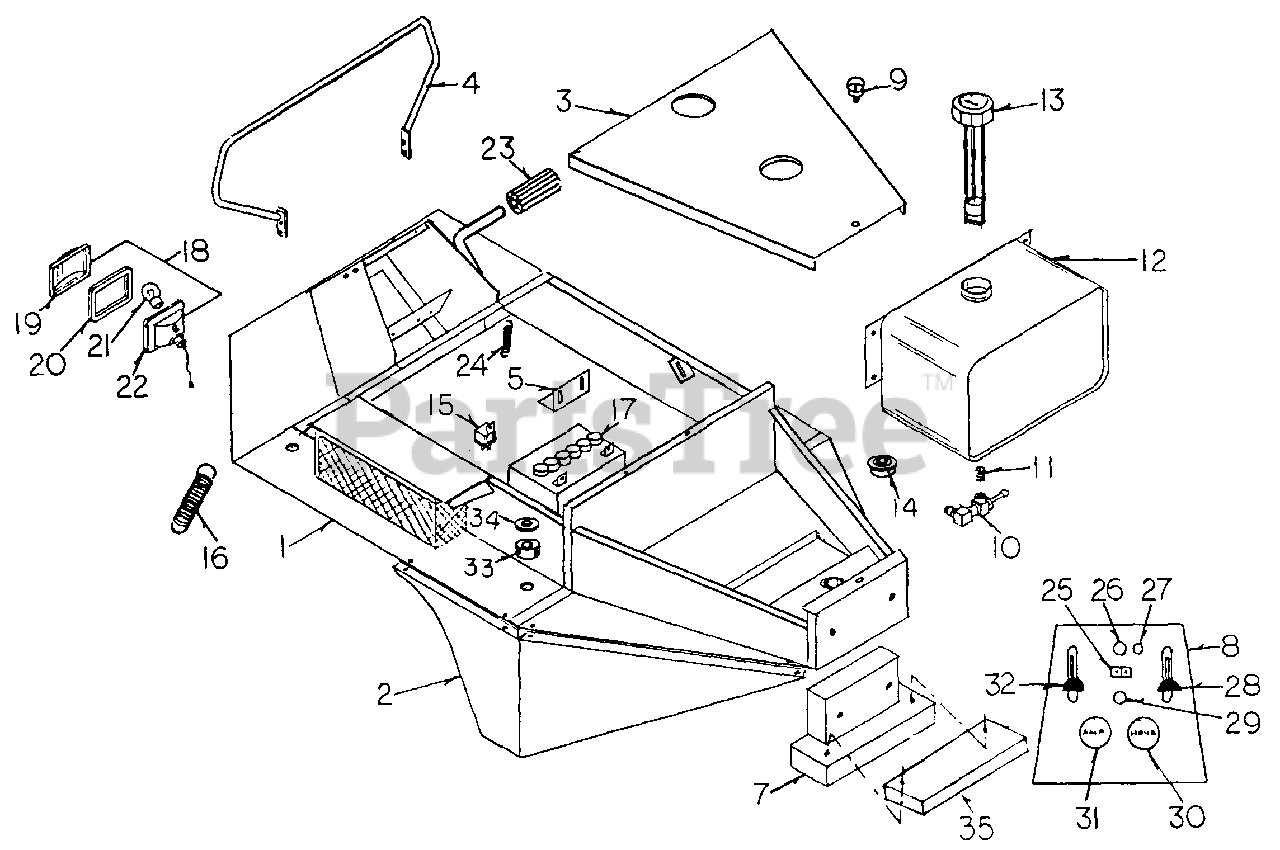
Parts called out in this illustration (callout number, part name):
2	Fender, LH
13	Fuel Tank Cap w/Gauge
15	Relay
17	Battery
18	Light Assembly
19	Lens
20	Gasket
21	Bulb
23	Brake Pedal Pad
25	Light Switch
26	Clutch Switch
28	Throttle Cable
29	Ignition Switch
33	Rubber Body Mount
34	Body Mount Washer
35	Tail Weight, 13 lb.
